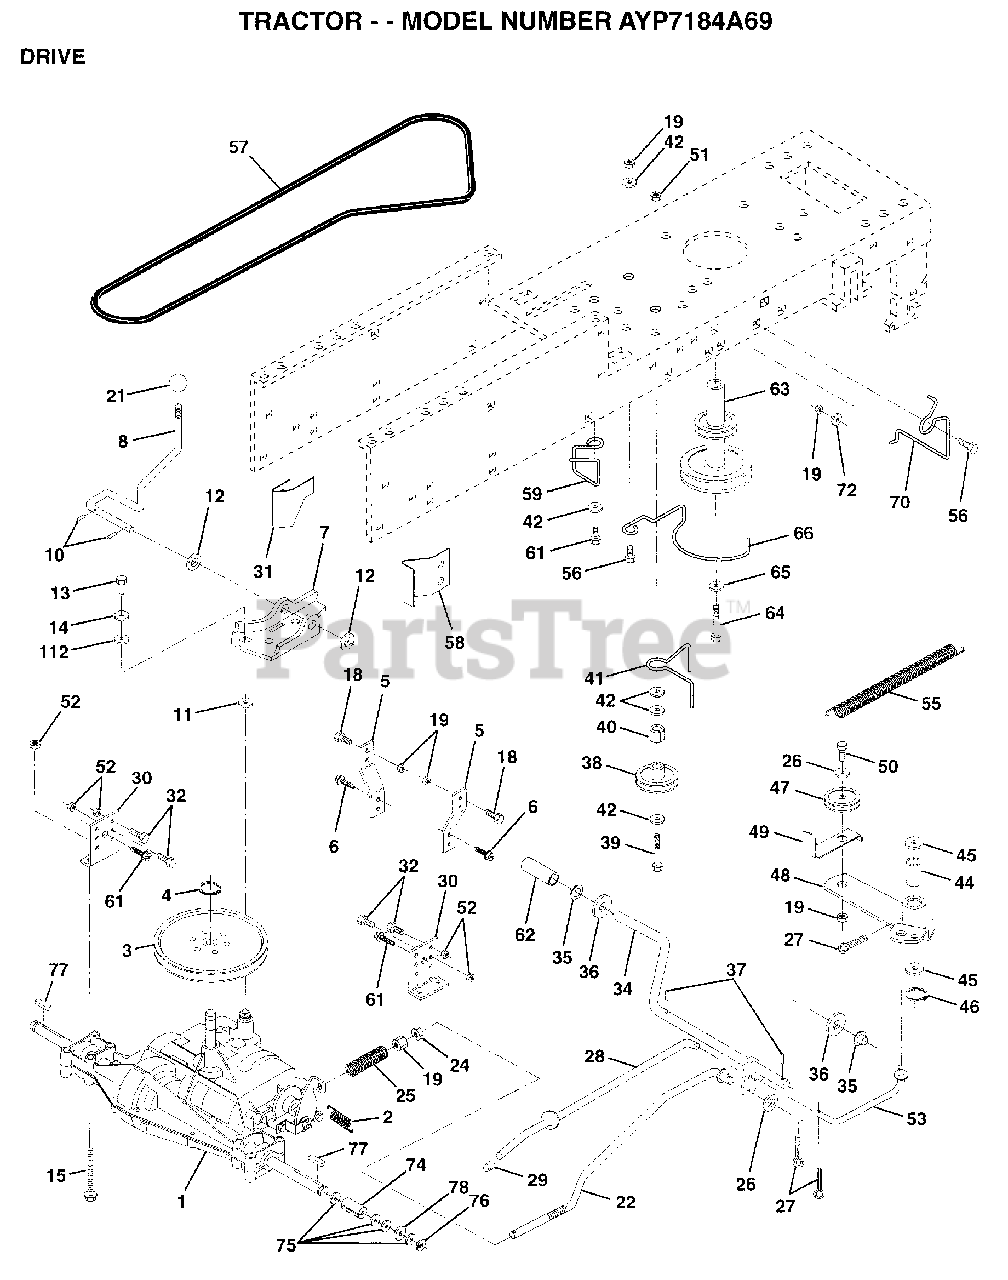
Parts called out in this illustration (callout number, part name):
2	SPRING.BRAKE.RETU
3	PULLEY TRANS
5	STRAP TORQUE
6	SCREW
8	SHIFT ROD
10	PIN COTTER 1/8
11	WASH-SHFT PLT LT
12	WASHER
13	BOLT.1/4-28.W/PAT
14	LOCKWASHER
15	BOLT.HX.FLG.5/16
18	BOLT
19	NUT
21	KNOB T (1/2-HOLE)
22	BRAKE ROD
24	NUT
25	SPRING ROD LT
26	WASHER
27	COTTER PIN
28	ROD.BRAKE.PARK.LT
29	PLUNGER CAP T
30	TRANSAXLE MTG BKT
31	"KEEPER,BELT LH T"
32	BOLT
34	SHAFT.PEDAL.FOOT
35	NYLON BEARING
36	WASHER LT
38	PULLEY.IDLER.FLAT
39	BOLT
40	SPACER T
41	BELT KEEPER LT
42	WASHER
44	"LY, BEARING"
45	WASHER LT
46	KLIP RING
48	ARM IDLER
49	RETAIN BELT
53	"LINK, CLUTCH T"
55	"SPRING, RETURN LT"
58	"KEEPER,BELT RH T"
59	KEEPER BELT CNTSP
61	SCREW
62	PEDAL COVER T
63	PULLEY.ENGINE
64	BOLT
65	LOCKWASHER
66	KEEPER.BELT.ENG.L
70	KEEPER BELT ENG
72	WASHER
74	SPACER LT
75	WASHER
76	E-RING LT
77	SQUARE KEY
78	WASHER
96	RETAINER M
112	WASHER LT
